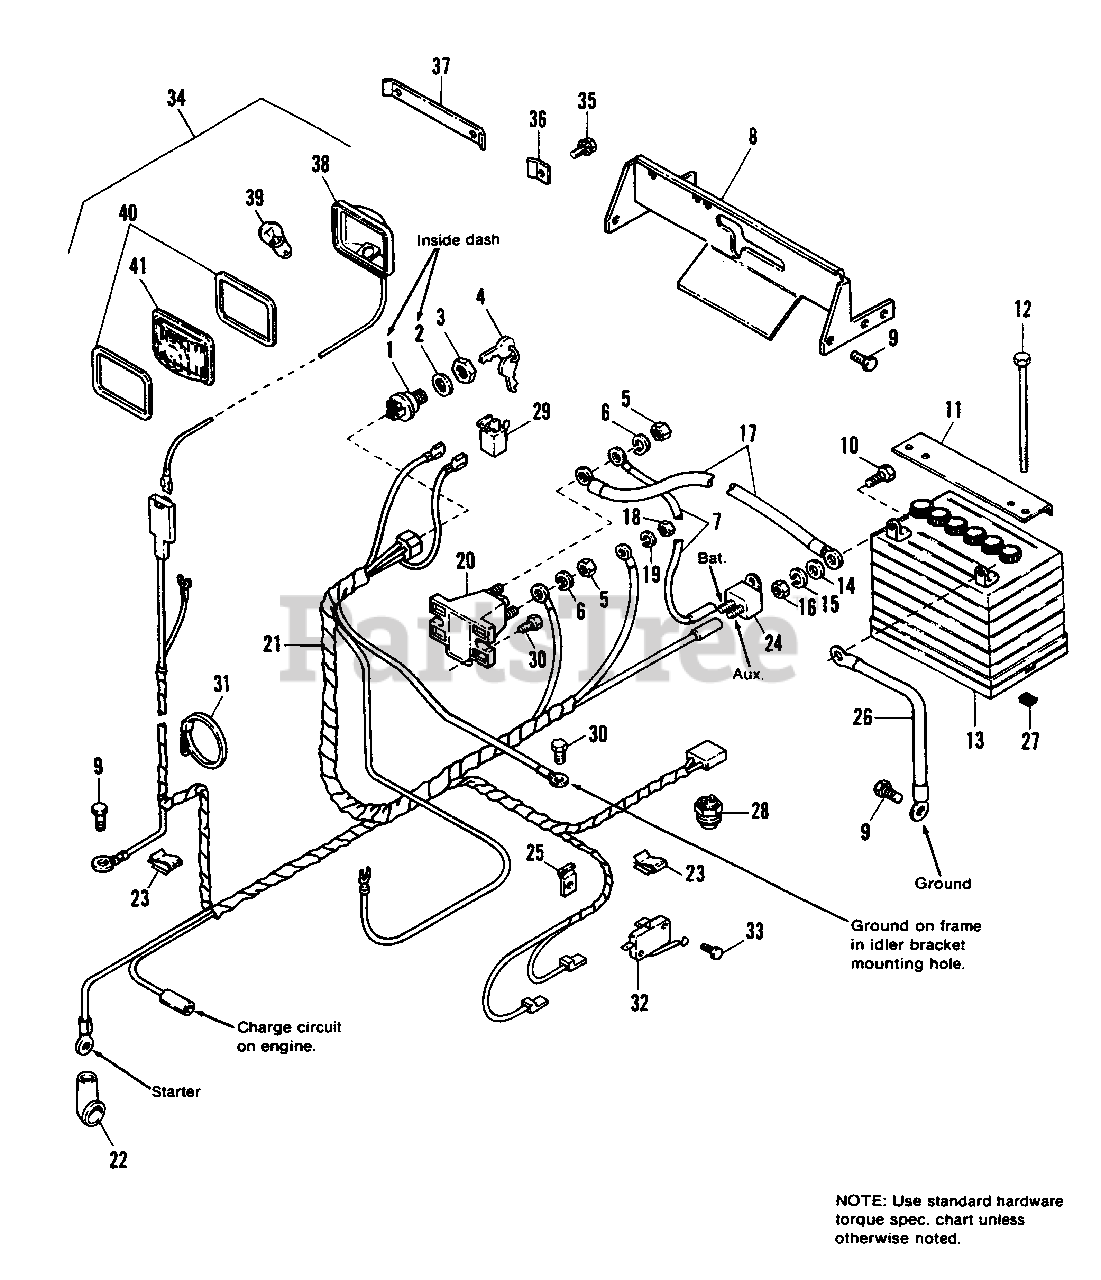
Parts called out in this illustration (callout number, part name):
1	SWITCH, Ignition
2	LOCKWASHER, Internal Tooth, 5/8
3	NUT, 5/8-32
5	NUT, Hex, 5/16-18
6	LOCKWASHER, 5/16
8	QUADRANT, Shift
9	SCREW, Taptite, 1/4-20 x 3/8
10	CAPSCREW, Hex, 1/4-20 x 3/4
11	CLAMP, Battery
12	CAPSCREW, Hex, 1/4-20 x 7
13	BATTERY SERVICE KIT
14	WASHER, 1/4
15	LOCKWASHER, 1/4
16	NUT, Hex, 1/4-20
18	NUT, Hex, #10-32
19	LOCKWASHER, Ext., #10
20	SOLENOID
21	HARNESS, Wiring
22	COVER, Terminal
23	CLIP, Speed
24	CIRCUIT BREAKER
27	NUT, Retainer, 1/4-20
28	SWITCH, PTO
29	SWITCH ASSY.
30	SCREW, Taptite, 1/4-20 x 3/4
32	SWITCH, Interlock
33	SCREW, Taptite, #5-40 x 3/4
34	LIGHT ASSY.
35	SCREW, Plastite, #10-14 x 1/2
36	CLIP, Headlight, Side
37	CLIP, Headlight, Center
38	REFLECTOR ASSY.
41	LENS, Plastic, Clear
